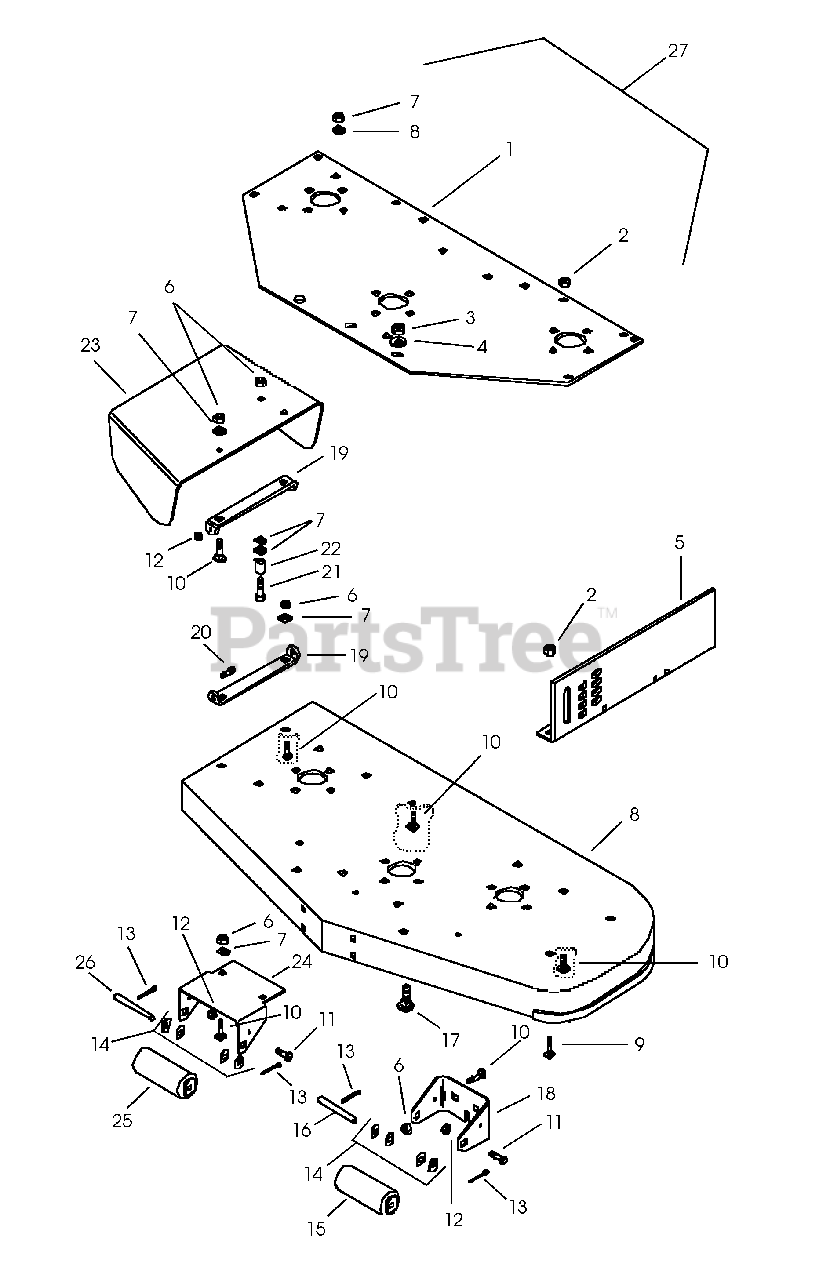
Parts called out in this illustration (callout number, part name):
1	Plate-Support
2	Nut-Locking-Center .31-18
3	Nut-Locking-Center .50-13
4	Washer-Flat-Steel .563 x 1.38 x .109
5	Bracket-Mower Side Support Left Hand
5	Bracket-Mower Side Support Right Hand
6	Nut-Locking-Center .38-16
7	Washer-Flat-Steel .406 x .812 x .065
8	Weldment-50" Mower Fabricated
9	Bolt-Round Head Square Neck .31-18 x 1.0
10	Bolt-Round Head Square Neck .38-16 x .75
11	Bolt-Hex .25-20 x .875
12	Nut-Locking-Center .25-20
13	Pin-Center .25 x 2.00
14	Washer-Flat-Steel .656 x 1.312 x .095
15	Roller-Gage
16	Rod
17	Bolt-Round Head Square Neck .50-13 x 1.00
18	Bracket-Roller
19	Bracket-Chute
20	Bolt-Hex .25-20 x 1.00 Grade 5
21	Bolt-Hex .38-16 x 1.50 Grade 5
22	Bushing-Sleeve .407 x .625 x .750
23	Shield-Safety External 50" Mower
24	Bracket-Roller Right Hand
25	Roller-Gage
26	Shaft-Center Roller
27	Deck-50" 3 Spindle PM100-Service
